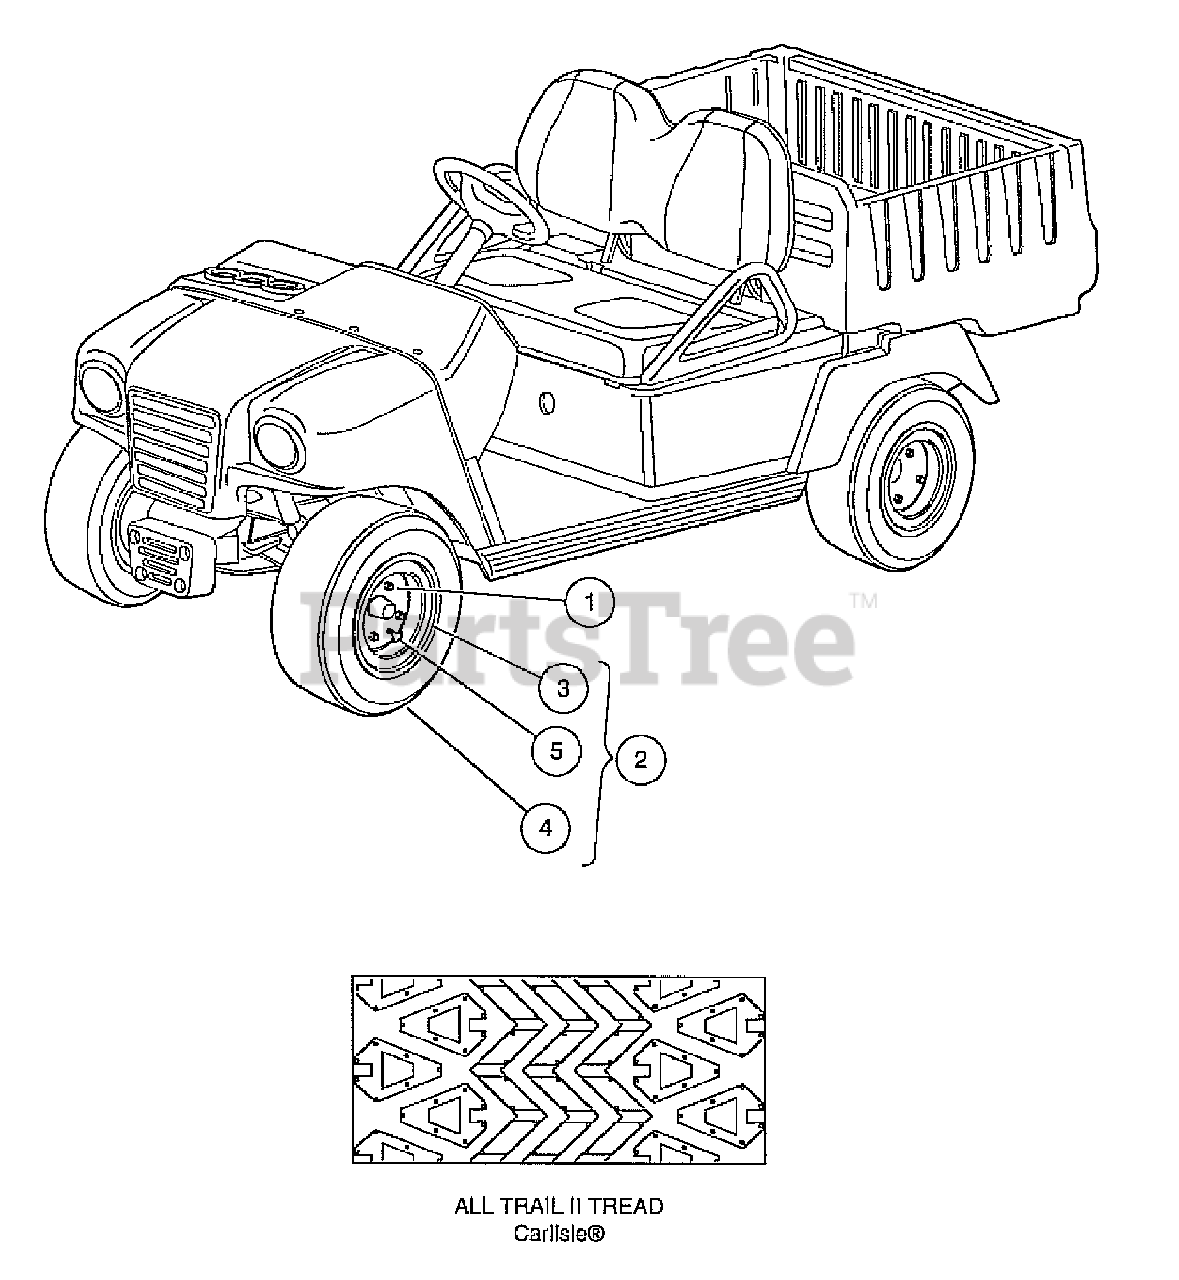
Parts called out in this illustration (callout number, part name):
1	Nut, 1/2-20 Lug
2	Tire Assembly, All Trail II
3	Wheel Rim, Gray
4	Tire, Unmounted, All Trail Il
5	Valve Stern
